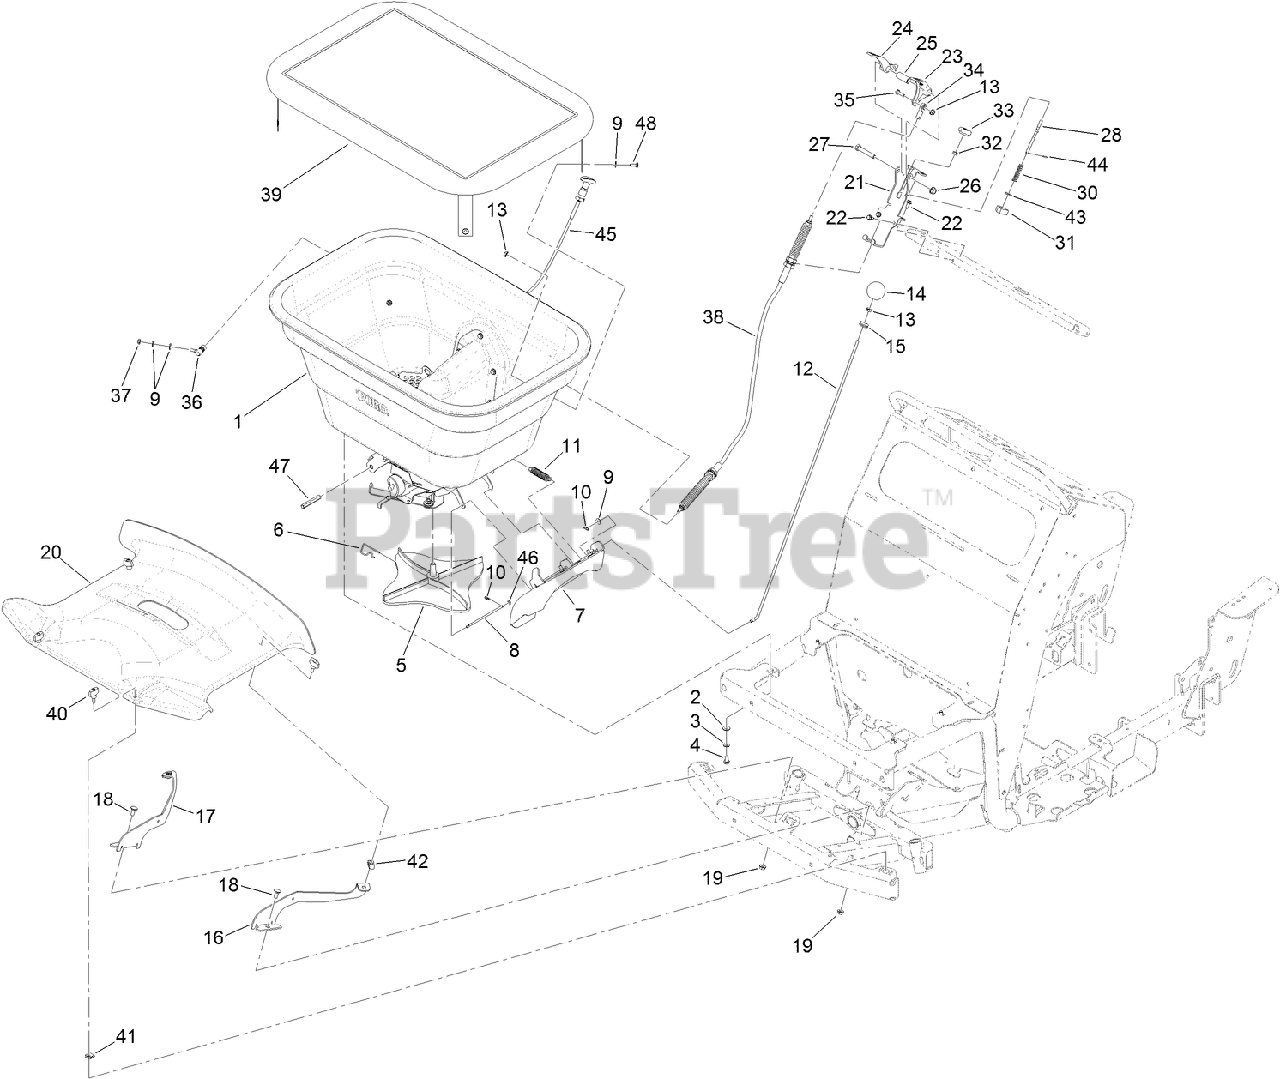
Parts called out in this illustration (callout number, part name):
1	SPREADER HOPPER ASM
2	WASHER
3	WASHER-LOCK
4	SCREW-HH
5	SPINNER-SPREADER
6	CLIP-SPINNER
7	SIDE DEFLECTOR ASM
8	PIN-DEFLECTOR
9	WASHER-FLAT
10	PIN-COTTER, HAIR
11	SPRING-EXTENSION
12	ROD-CONTROL, DEFLECTOR
13	NUT-HF
14	KNOB-RATE, FLOW
15	GROMMET
16	BRACKET-COVER, FRONT (LH)
17	BRACKET-COVER, FRONT (RH)
18	SCREW-CARR
19	NUT-HF
20	COVER-FRONT, SPREADER/SPRAYER
21	MOUNT-HANDLE
22	SCREW-HWH
23	LEVER-SPREAD, WIDE
24	LEVER-SPREAD, NARROW
25	SPACER
26	NUT-HF
27	SCREW-HH
28	LINK-ADJUST, NARROW
30	SPRING-COMPRESSION, BAIL
31	STOP-SPREAD, NARROW
32	NUT-COUPLER
34	ROD END-BALL JOINT
35	SCREW-HH
36	BALL-JOINT
37	NUT-HEX, NI
39	COVER-HOPPER
40	KNOB-T
41	NUT-RETAINER, U STYLE
42	NUT-RETAINER
43	WASHER-FLAT
44	PIN-COTTER
45	CABLE-CONTROL, TURN LOCK
46	WASHER-FLAT
47	POST-HEX, DIFFUSER GUIDE
48	SCREW-HH
